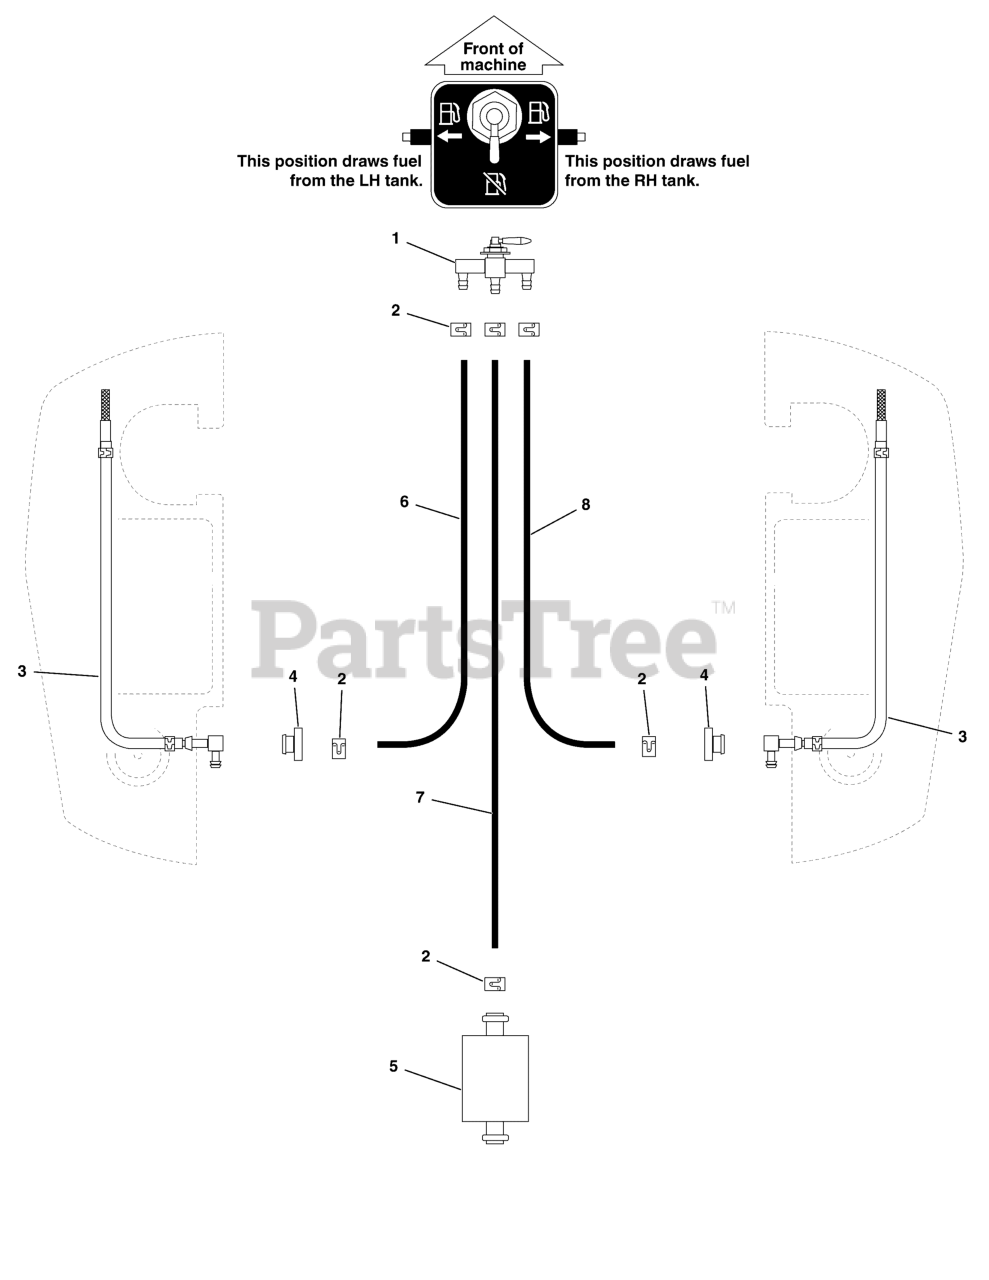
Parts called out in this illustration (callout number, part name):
1	VALVE, FUEL STRAIGHT, OUTLET
2	CLAMP, Hose
3	PICKUP TUBE ASSEMBLY, FUEL LINE (SV)
4	BUSHING-FUEL TANK RED RUBBER
5	FUEL FILTER (SV)
6	HOSE, 1/4" FUEL, 13.00"
7	HOSE, 1/4" FUEL, 10.50"
8	HOSE, 1/4" FUEL, 33.50"
